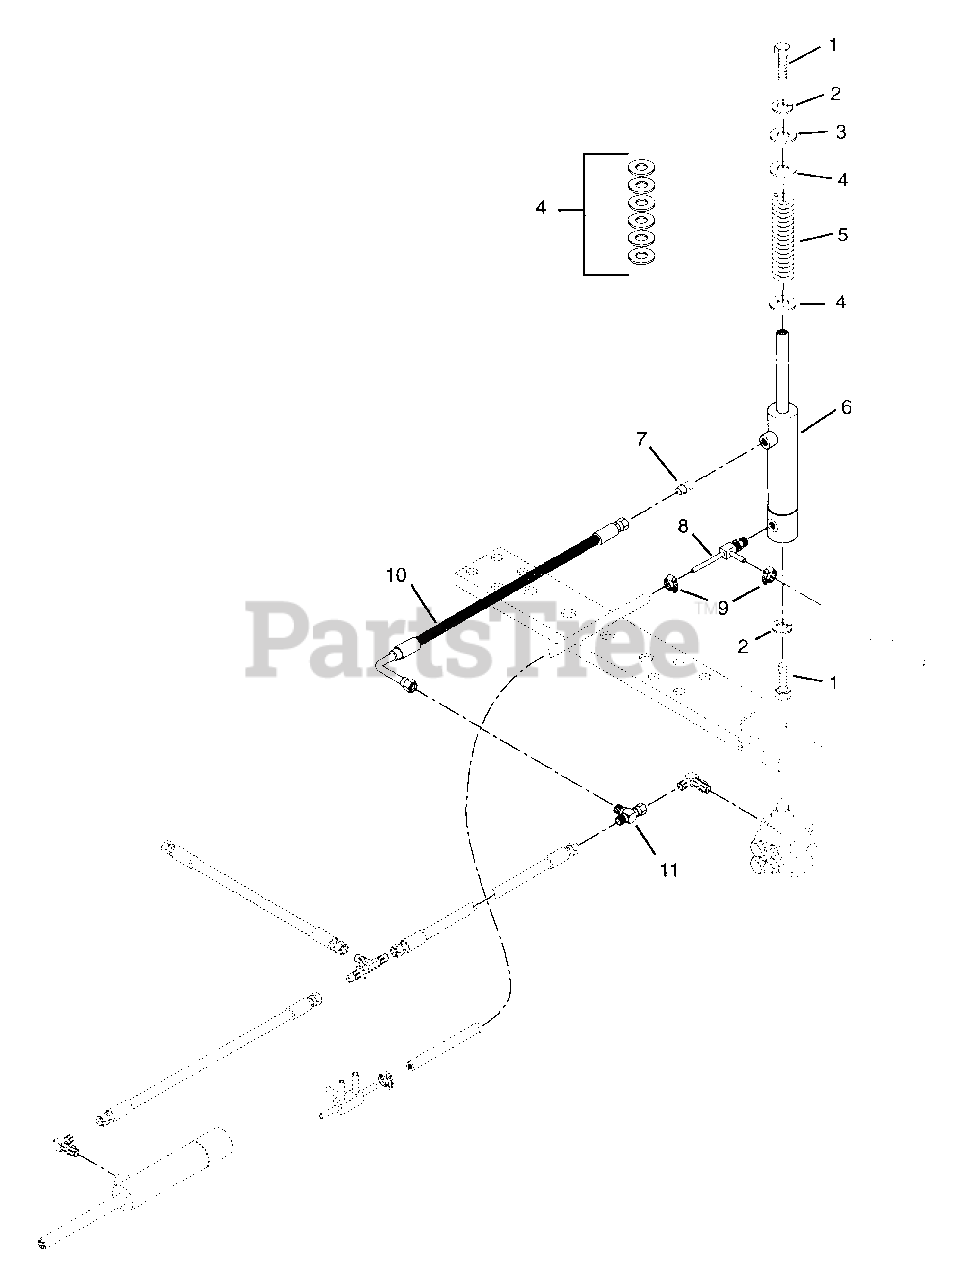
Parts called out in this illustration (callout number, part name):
1	Bolt-Hex .50-20 x 1.00 Grade 8
2	Washer-Lock .50 Reg.
3	Washer-Flat-Steel .531 x 1.250 x .100
4	Washer-Flat-Steel .700 x 1.470 x .134
5	Spring, Compression .207 x 1.25 x 6
6	Cylinder, Lift Assist
7	Adapter-Pipe .56-18 "O" Ring to .56-18
8	Adapter-Barb tee .38 to .56-18 w/ "O" Ring
9	Hose Clamp
10	Hose, PSU to Tank
11	Adapter-Pipe .56-18 to .56-18
